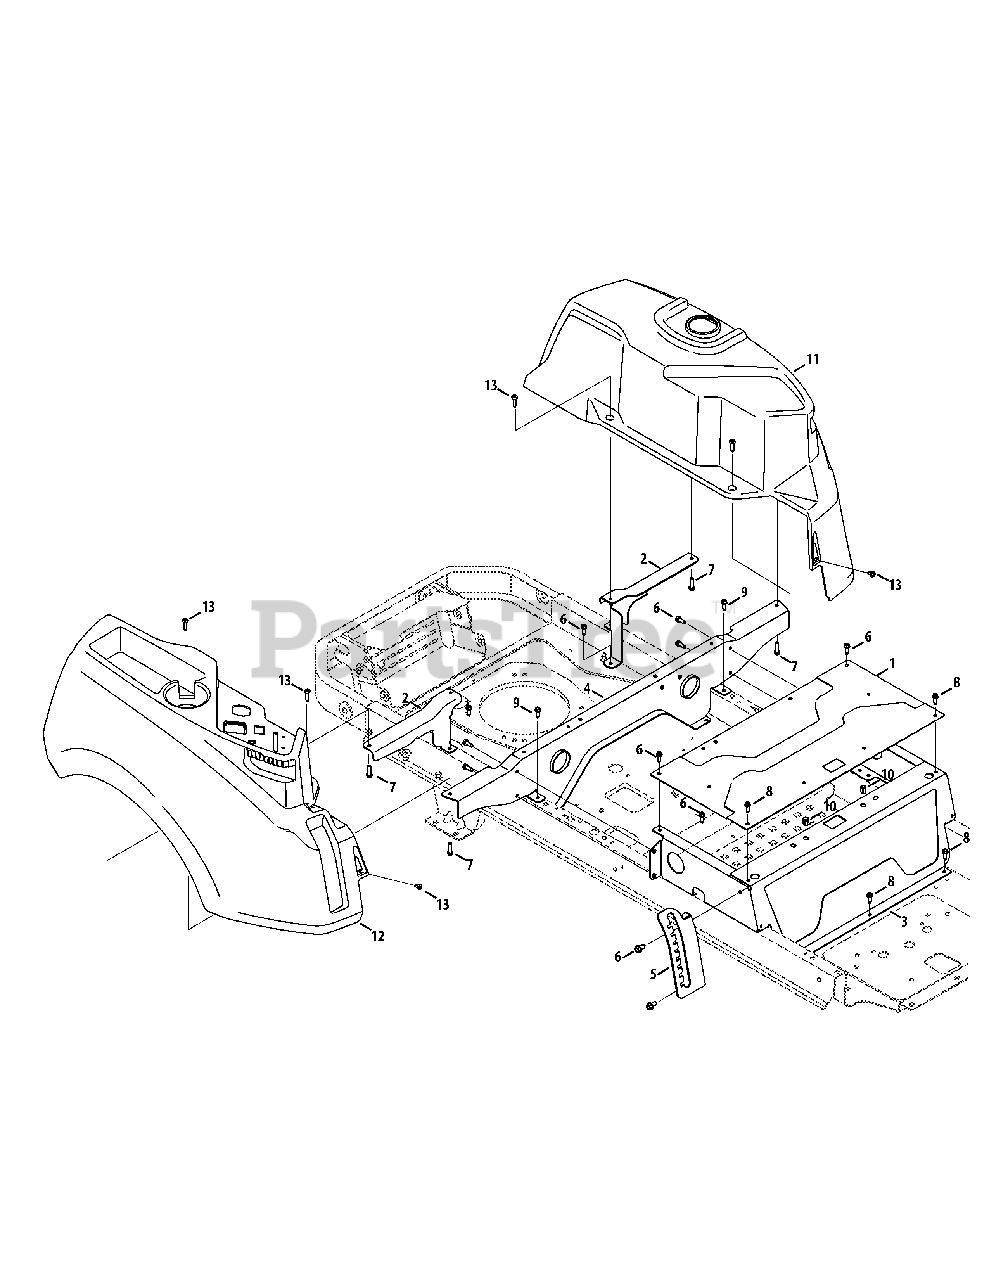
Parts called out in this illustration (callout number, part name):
1	Seatbox Plate
2	Rear Tank Bracket
4	Rear Seatbox Brace
5	Height Index Bracket
6	Hex Washer Screw, 5/16-18 x .750
7	Hex Washer Screw, 5/16-14 x 1.00
8	Self Tapping Screw, 5/16-18 x .750
9	Hex Washer Screw, 5/16-18 x .50
10	Nut, 5/16-18
11	LJ Console
12	RH Console
13	Shoulder Screw, 1/4-20
